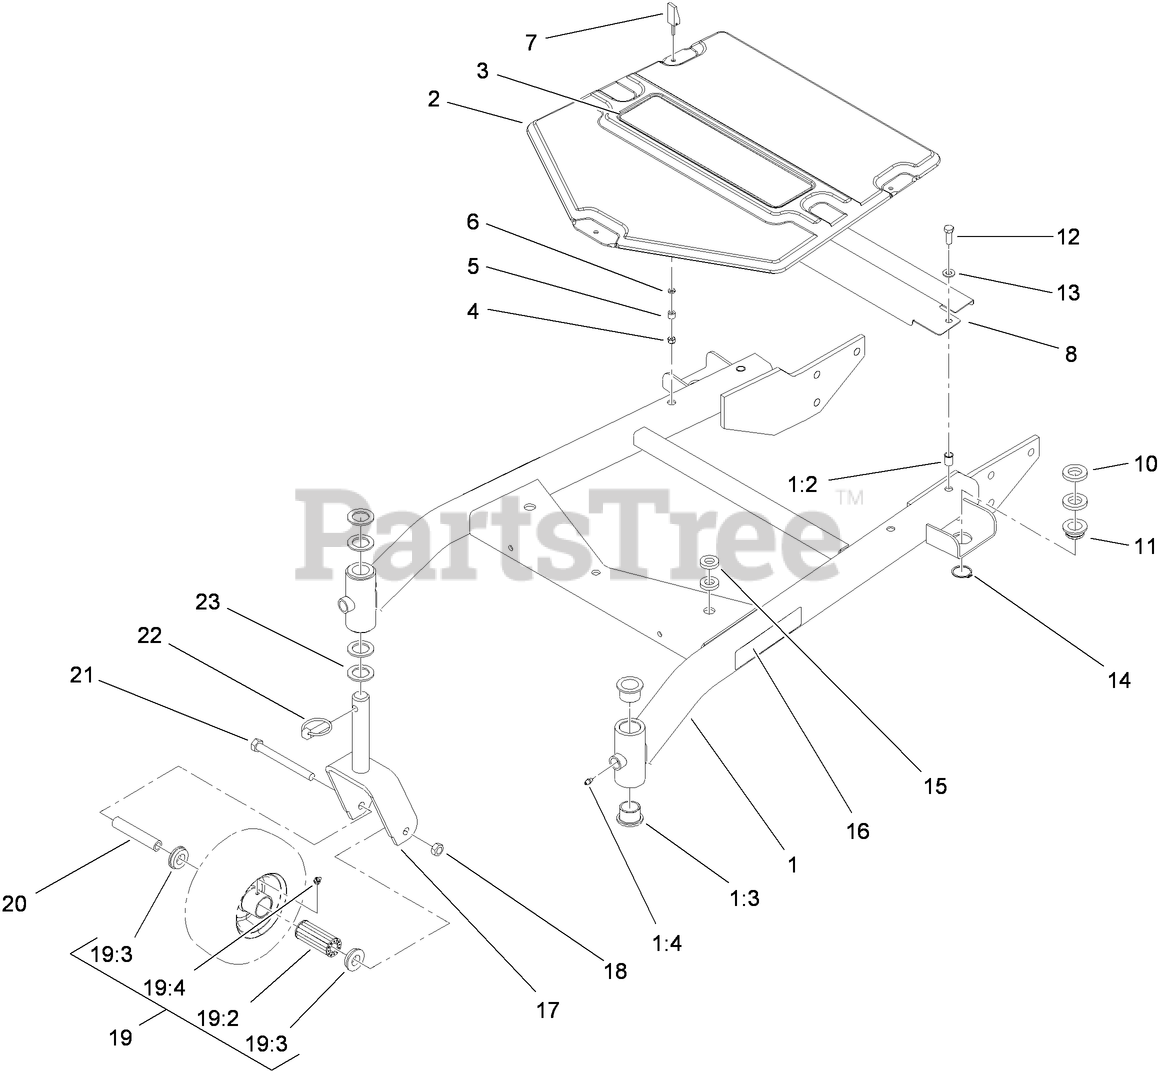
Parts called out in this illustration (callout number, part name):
1	CARRIER FRAME ASM
1:2	INSERT-NUT
1:3	BUSHING
1:4	FITTING-GREASE
2	COVER-FRAME, CARRIER
4	NUT-LOCK, HH
5	BUSHING-LATCH, SWELL
6	WASHER
7	HANDLE-LATCH, SWELL
8	SHIELD-BELT
10	SPACER-SUPPORT, DECK
11	BUSHING-DECK
12	SCREW-HH
13	WASHER-FLAT
14	RING-RETAINING
15	SPACER
16	DECAL-HOC
17	FORK-CASTOR
18	NUT-HEX
19	WHEEL AND TIRE ASM
19:2	BEARING-ROLLER
19:3	BUSHING
19:4	FITTING-GREASE
20	BUSHING-SPANNER
21	SCREW-HH
22	PIN-LYNCH
23	WASHER-THRUST
